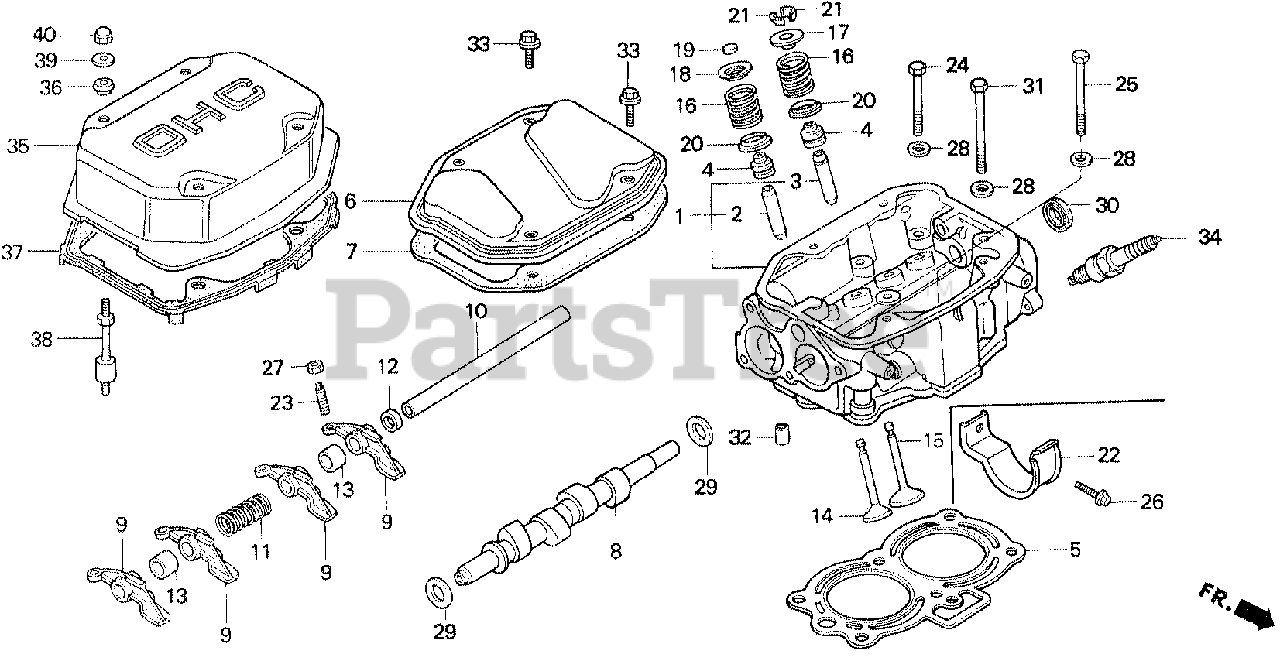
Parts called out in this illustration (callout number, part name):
1	CYLINDER HEAD
2	GUIDE, EX. VALVE
3	GUIDE, VALVE (OS)
4	SEAL, VALVE STEM
5	GASKET, CYLINDER HEAD
8	CAMSHAFT
9	ARM, VALVE ROCKER
10	SHAFT, VALVE ROCKER ARM
11	SPRING, VALVE ROCKER ARM
12	COLLAR A, VALVE ROCKER ARM
13	COLLAR B, VALVE ROCKER ARM
14	VALVE, IN.
15	VALVE, EX.
16	SPRING, VALVE
17	RETAINER, VALVE SPRING
18	RETAINER, VALVE SPRING
19	ROTATOR, VALVE
20	SEAT, VALVE SPRING
21	COTTER, VALVE
23	SCREW, TAPPET ADJ.
24	BOLT, HEAD (8X70)
25	BOLT, HEX. (8X55)
27	NUT, TAPPET ADJ.
28	WASHER, HEAD (8MM)
29	WASHER, THRUST (16MM)
30	OIL SEAL (16X28X6)
31	BOLT, HEX. (8X100)
32	PIN A, DOWEL (10X16)
34	SPARK PLUG (BPR5HS) (NGK)
34	SPARK PLUG (W16FPR) (DENSO)
34	SPARK PLUG (BPR6HS) (NGK)
34	SPARK PLUG (W20FPR) (DENSO)
34	SPARK PLUG (BPR7HS) (NGK)
35	COVER, CYLINDER HEAD
36	WASHER, HEAD COVER
37	GASKET, HEAD COVER
38	BOLT, SPECIAL STUD
39	WASHER (6X17)
40	NUT, CAP (6MM)
